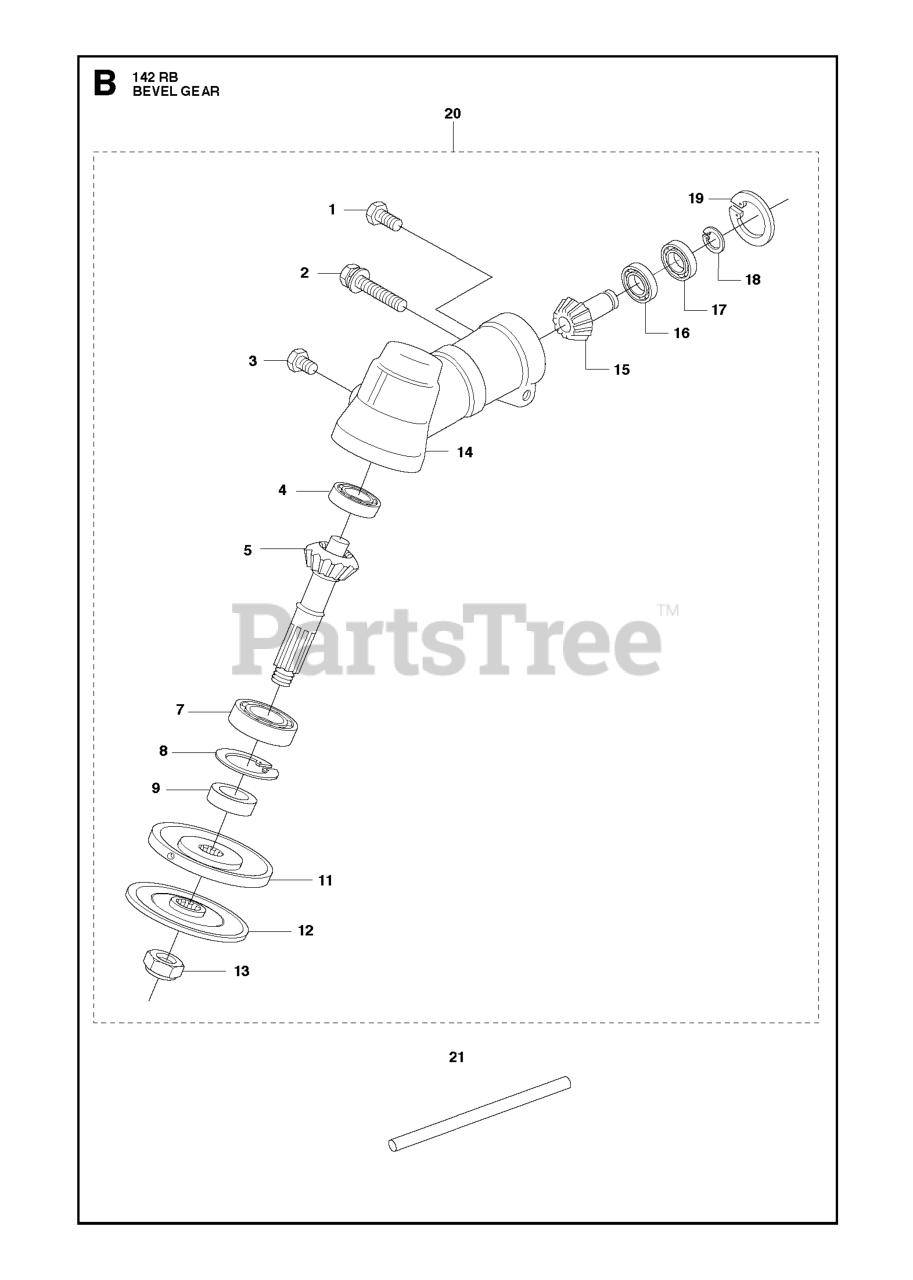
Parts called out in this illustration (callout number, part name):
2	SCREW M6S 6X30
12	FLANGE/BOSS
18	RETAINING RING SGA 10
19	RETAINING RING SGH 26
21	HOLDER
